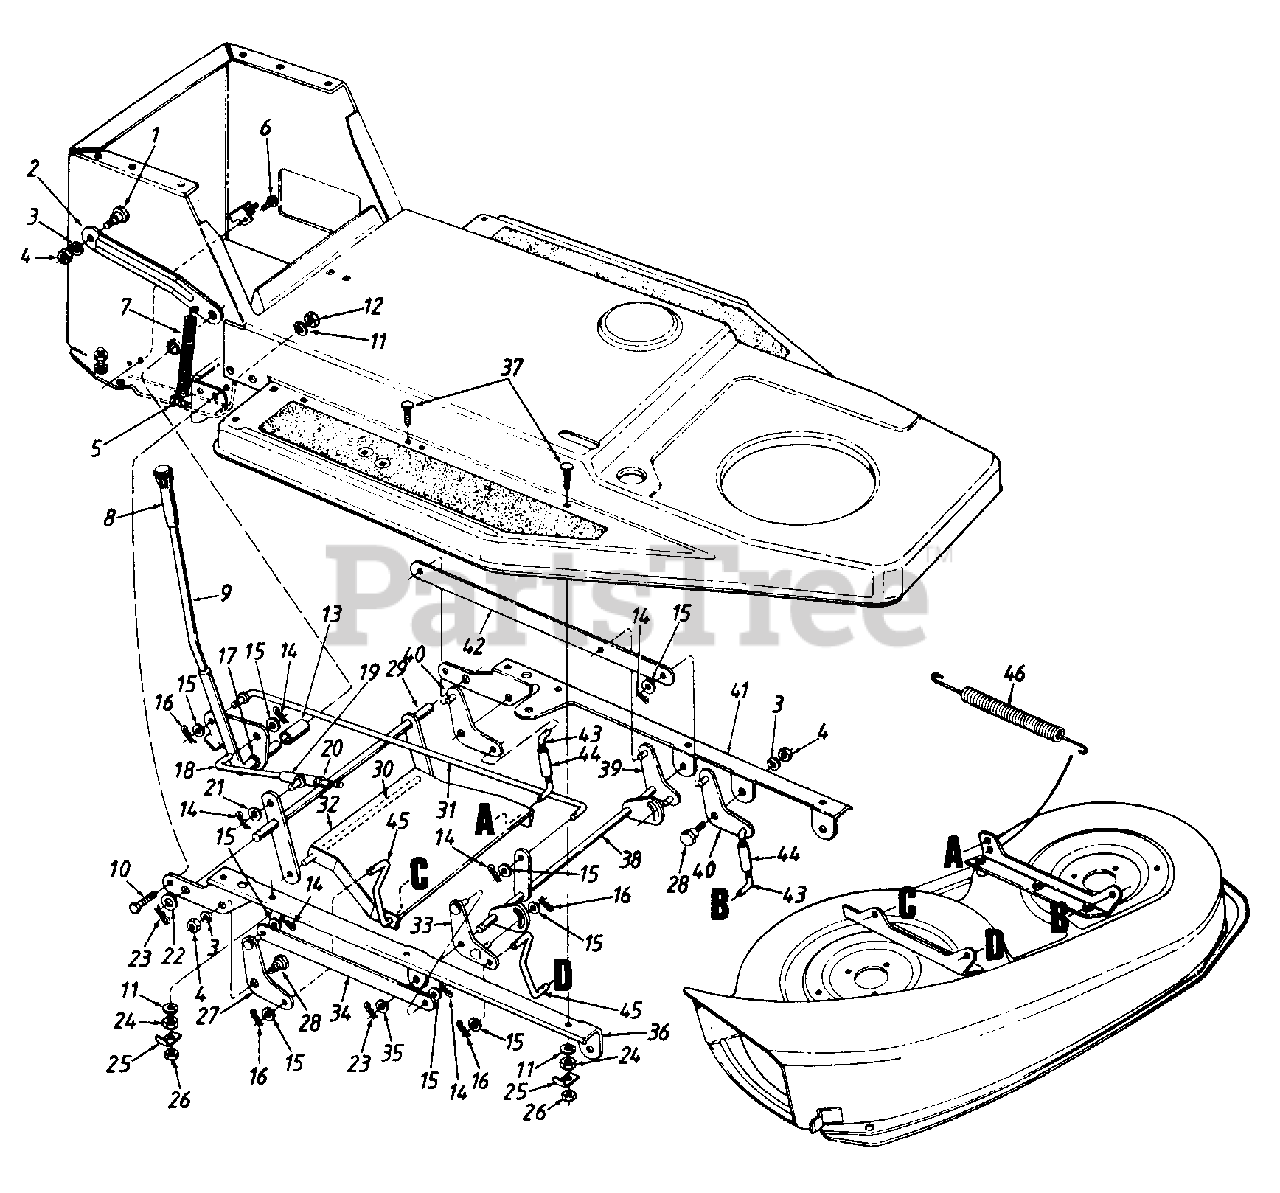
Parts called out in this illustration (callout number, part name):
1	Shld. Bolt .5" Dia. x .25" Lg.
4	Hex Nut 3/8-16 Thd.*
5	Hex Bolt 1/4-28 x 1.25" Lg.
6	Hex Wash. Hd. TT-Tap Scr. 1/4-20 x .5" Lg.
7	Ext. Spring
9	Deck Lift Handle Ass'y.
10	Hex Wash. TT-Tap Scr. 5/16-18 x .62" Lg.
11	L-Wash. 5/16" I.D.
12	Hex Nut 5/16-18 Thd.
13	Nylon Sleeve Brg.
14	Cot-Pin 3/32" Dia. x .75" Lg.
15	Fl-Wash. .406" I.D. x .75" O.D.
16	Internal Cot-Pin 5/16" Dia.
17	Nyliner Flanged Brg.
18	Deck Engagement Rod
19	Pivot Sleeve Ass'y.
20	Hex L-Nut 3/8-16 Thd.
21	Thrust Washer .382" I.D.
22	Fl-Wash. .635" I.D. x 1.04" O.D.
23	Cot-Pin 1/8 Dia. x 1.25" Lg.
24	Hex Nut 5/16-24 Thd.
25	Harness Retainer
26	Hex Cent. L-Nut 5/16-24 Thd.
27	Deck Pivot Brkt. Ass'y.-R.H. Rear
28	Shld. Bolt .625" Dia. x .170" Lg.
31	Deck Lift Rod
32	Deck Stabilizer Brkt.
44	Adj. Lift Link Ass'y.
45	Deck Hanger
46	Deck Spring 10.33" Lg.
